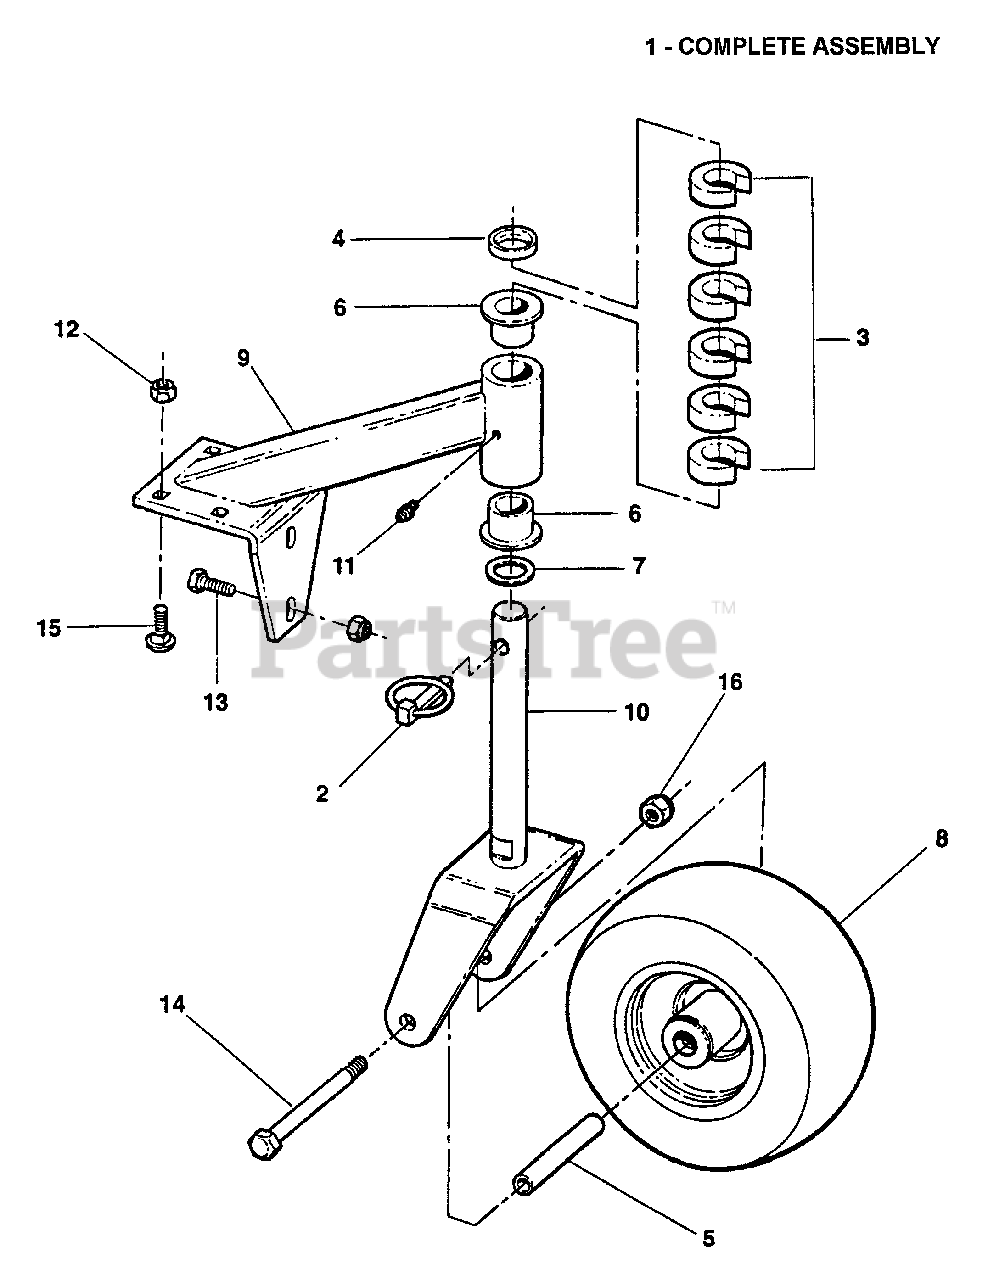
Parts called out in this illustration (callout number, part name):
1	ASSEMBLY, Rear Caster, 73" OFZ Deck
2	PIN, 7/16" Lynch (HD)
3	SPACER, Caster
4	SPACER, 1" x 1 3/8 x .30" (PM)
5	SPACER, Axle Sleeve
6	BUSHING, Caster
7	BUSHING, 1" Machine
8	ASSEMBLY, Wheel/Tire, 9 x 3.50 - 4
9	SUPPORT, Caster (Weldment)
10	YOKE, Caster (Weldment)
11	FITTING, Lube, 1/4-28 Straight
12	NUT, 3/8-16 HEX NYLON LOCK
13	BOLT, 3/8-16 X 1" GD5 CZ
14	BOLT, 1/2-13 X 5-1/2" GD5 YZ
15	BOLT, 3/8-16 x 1" Carriage
16	NUT, 1/2-13 HEX NYLON LOCK
